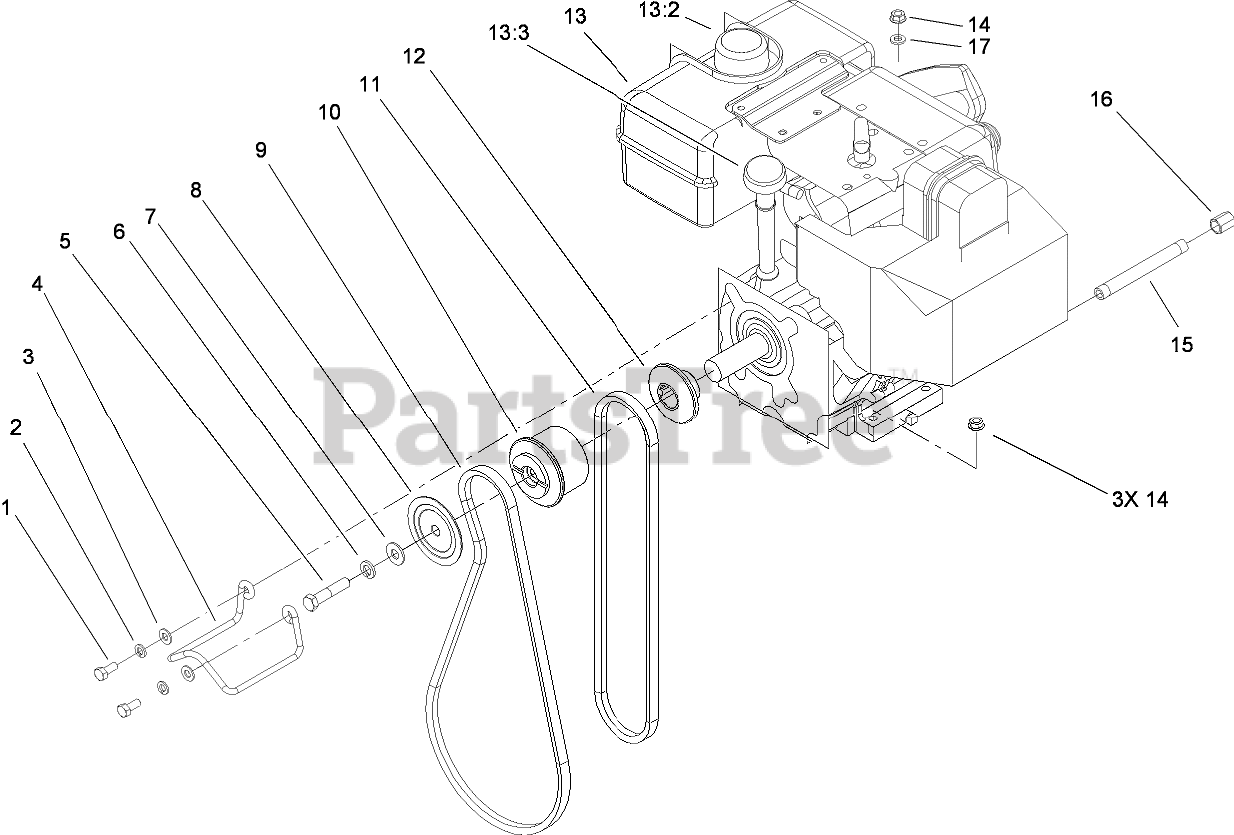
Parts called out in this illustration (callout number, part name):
1	SCREW-HH
2	WASHER-LOCK
3	WASHER-PLAIN
4	GUIDE-BELT
5	SCREW-HH
6	WASHER-LOCK
7	WASHER-FLAT
8	SHEAVE-HALF, IMPELLER
9	BELT-V
10	PULLEY-ENGINE, CENTER
11	V BELT-TRACTION
12	SHEAVE-HALF, TRACTION
13:2	CAP-FUEL
13:3	DIPSTICK
14	NUT-HF
15	NIPPLE-PIPE
16	CAP-PIPE
17	WASHER-FLAT
